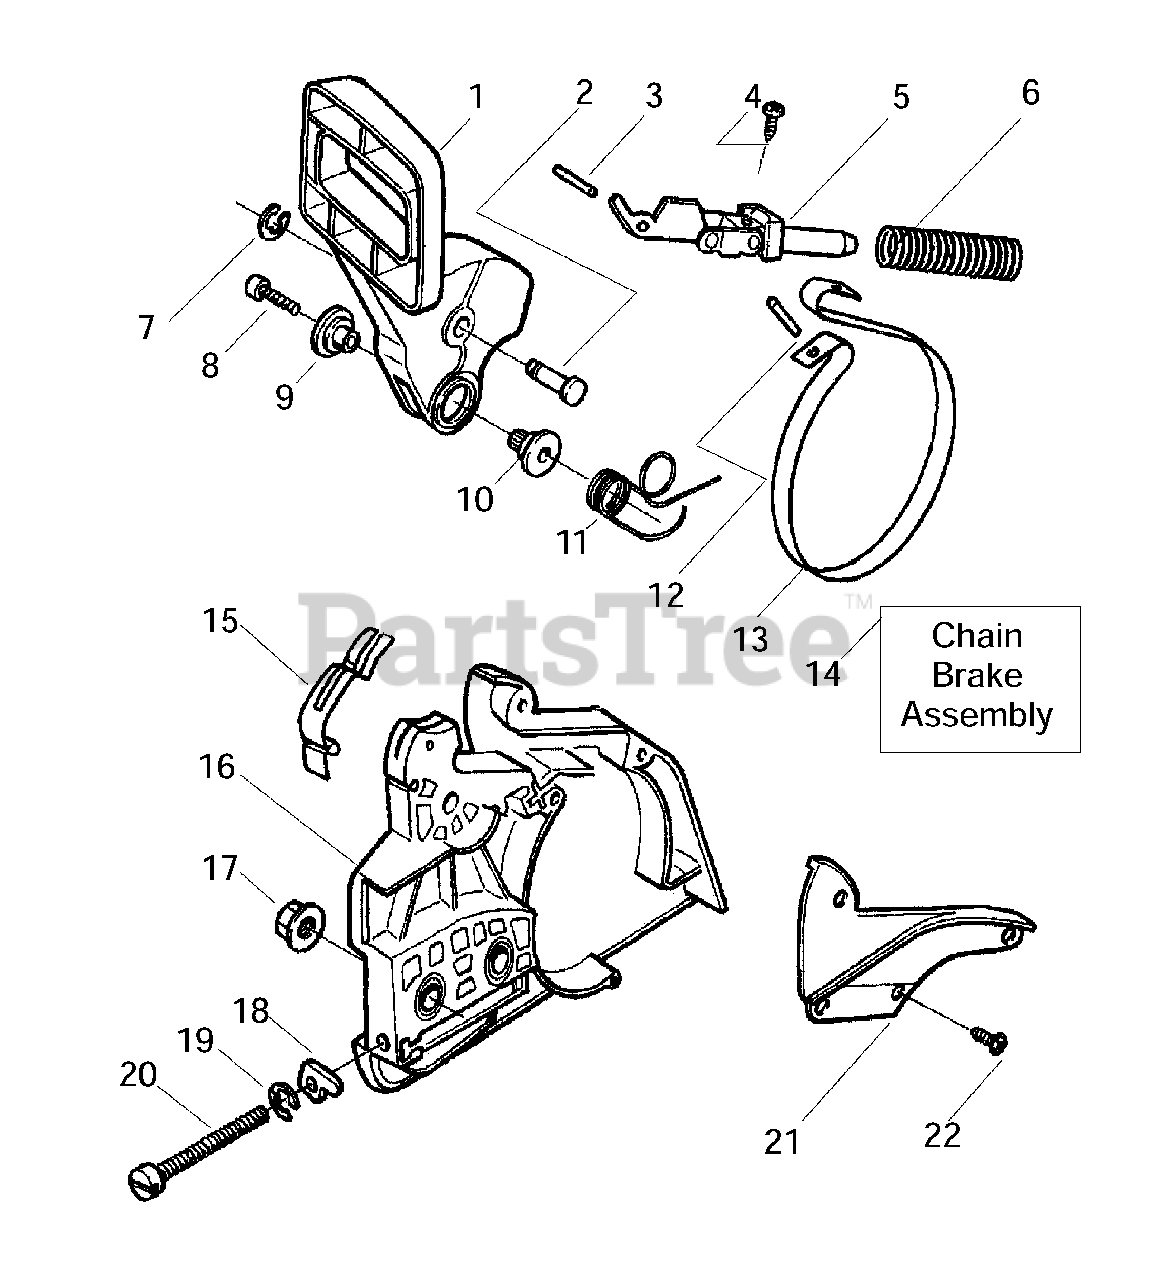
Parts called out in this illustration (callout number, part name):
1	Actuating Lever
4	Screw
5	Front Link Ass'y.
6	Chain Brake Spring
9	Journal-Right
10	Journal-Left
11	Handguard Spring
12	Pin-Spring
13	Brake Band
14	Chain Brake Assembly
15	Position Spring
16	Clutch Cover
18	Bar Adjusting Pin
20	Screw-Bar Adjusting
21	Chain Brake Spring Cover
22	Screw
